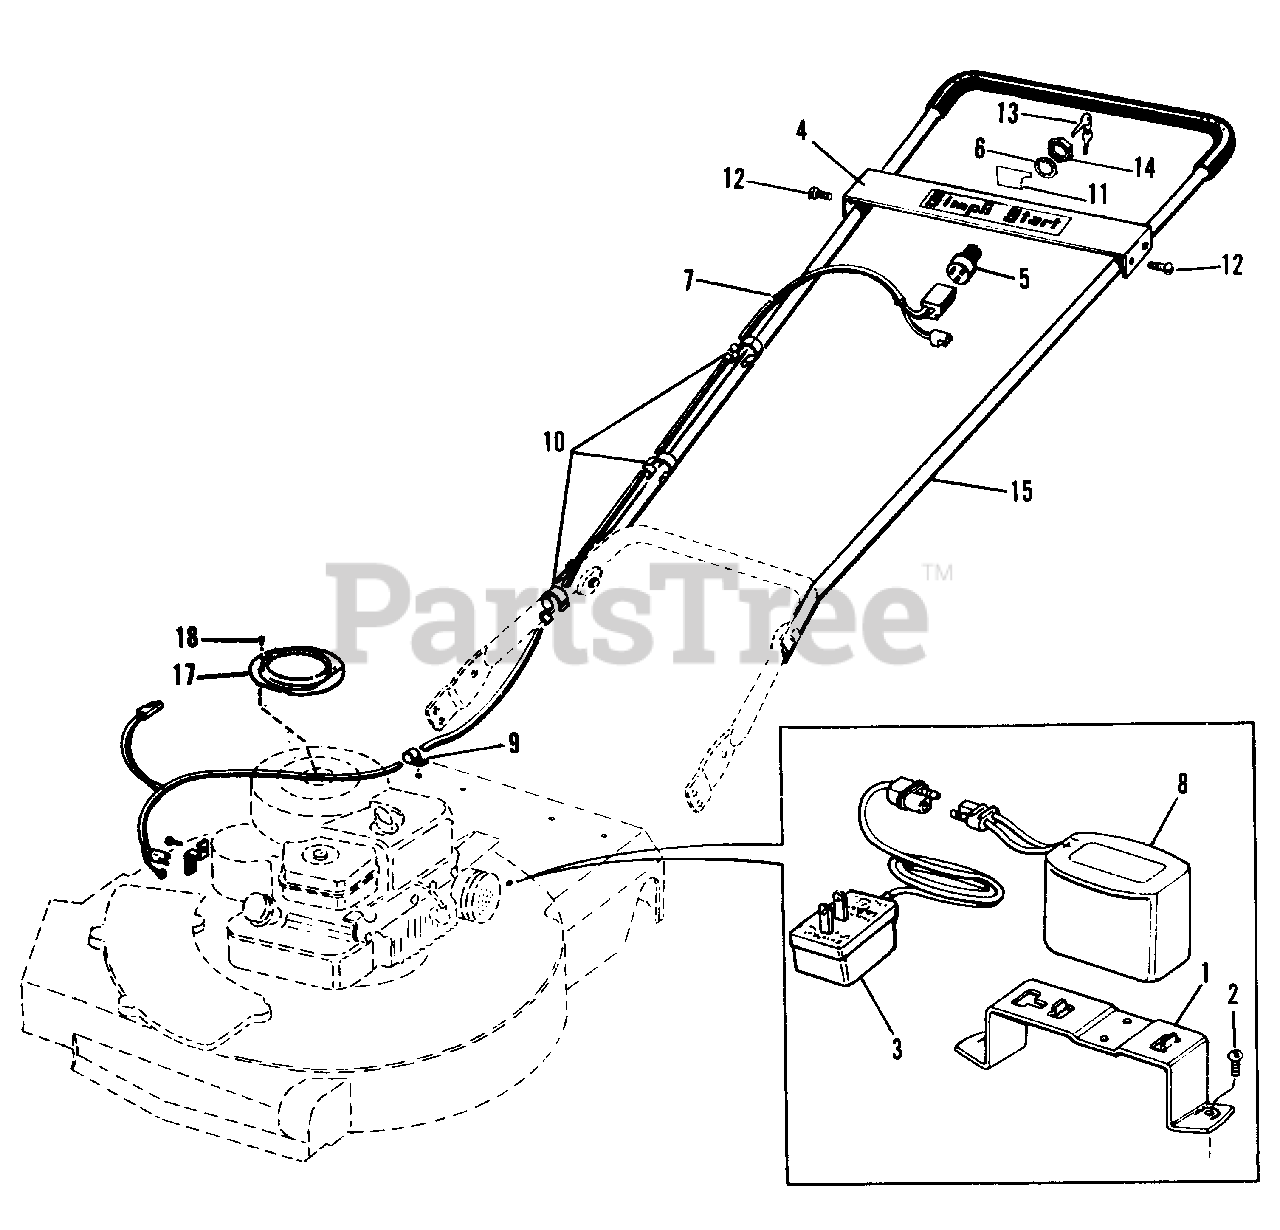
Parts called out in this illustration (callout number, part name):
1	BATTERY SUPPORT ASSY
2	RIVET, Pop, Clip
3	CHARGER, Battery
4	PANEL, Mounting Switch
5	SWITCH, Key
6	LOCKWASHER, 9/16 Inter. Tooth
7	HARNESS ASSY
8	CLAMP, Cable
9	CLAMP, Cable BATTERY ASSY
10	CLAMP, Cable Handle
11	FILM, Ignition
12	SCREW, Thd. Forming, 1/4-20 x 3/8
13	KEY & RING ASSY
14	NUT, Hex Special
15	HANDLE, Upper
15	HANDLE, Upper (Mfg. No. 990681)
16	FlLM, "Simpli-Start"
17	RING, Support
18	SCREW, Thd.Forming, #4-40 x 1/4
